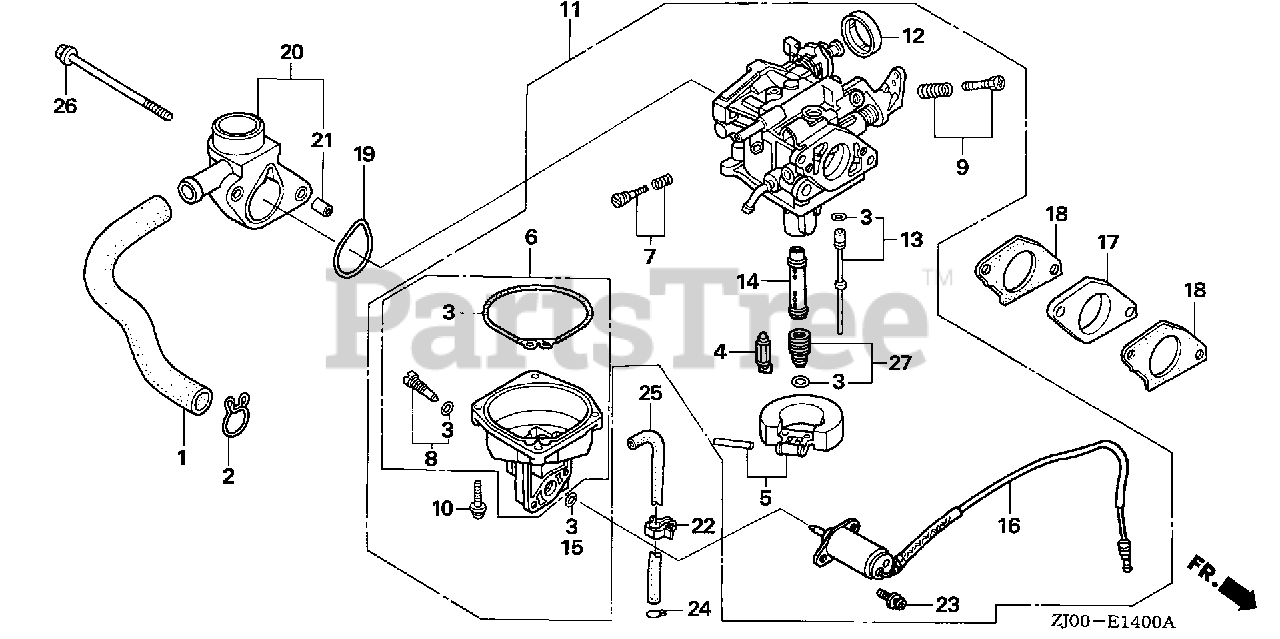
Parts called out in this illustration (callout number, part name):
1	TUBE, BREATHER
2	CLIP, BREATHER TUBE
3	GASKET SET (CARBURETOR NO.)
4	VALVE SET, FLOAT
6	CHAMBER SET, FLOAT (CARBURETOR NO.)
7	SCREW SET (CARBURETOR NO.)
8	SCREW SET, DRAIN
9	SCREW SET (CARBURETOR NO.)
10	SCREW-WASHER
11	CARBURETOR ASSY. (BG21A A/B)
11	CARBURETOR ASSY. (BG21E B)
12	CAP, CHOKE DUST
13	JET SET (#45) (CARBURETOR NO.) (NOT AVAILABLE)
13	JET SET (#60) (CARBURETOR NO.)
14	NOZZLE, MAIN
14	NOZZLE, MAIN (CARBURETOR NO.) (NOT AVAILABLE)
15	O-RING (5.8X1.9) (CARBURETOR NO.)
16	VALVE ASSY., SOLENOID (CARBURETOR NO.)
17	INSULATOR, CARBURETOR
18	GASKET, CARBURETOR
19	GASKET, AIR CLEANER
20	ELBOW, AIR CLEANER
21	COLLAR, DISTANCE
22	CLIP B, CABLE (9MM BLACK)
23	SCREW-WASHER (5X12)
24	CLIP, TUBE (B8)
25	BULK HOSE, VACUUM (4.5X1000) (4.5X460)
26	BOLT, FLANGE (6X105)
27	JET SET, MAIN (#82) (CARBURETOR NO.)
27	JET SET, MAIN (#85) (CARBURETOR NO.)
27	JET SET, MAIN (#88) (CARBURETOR NO.)
